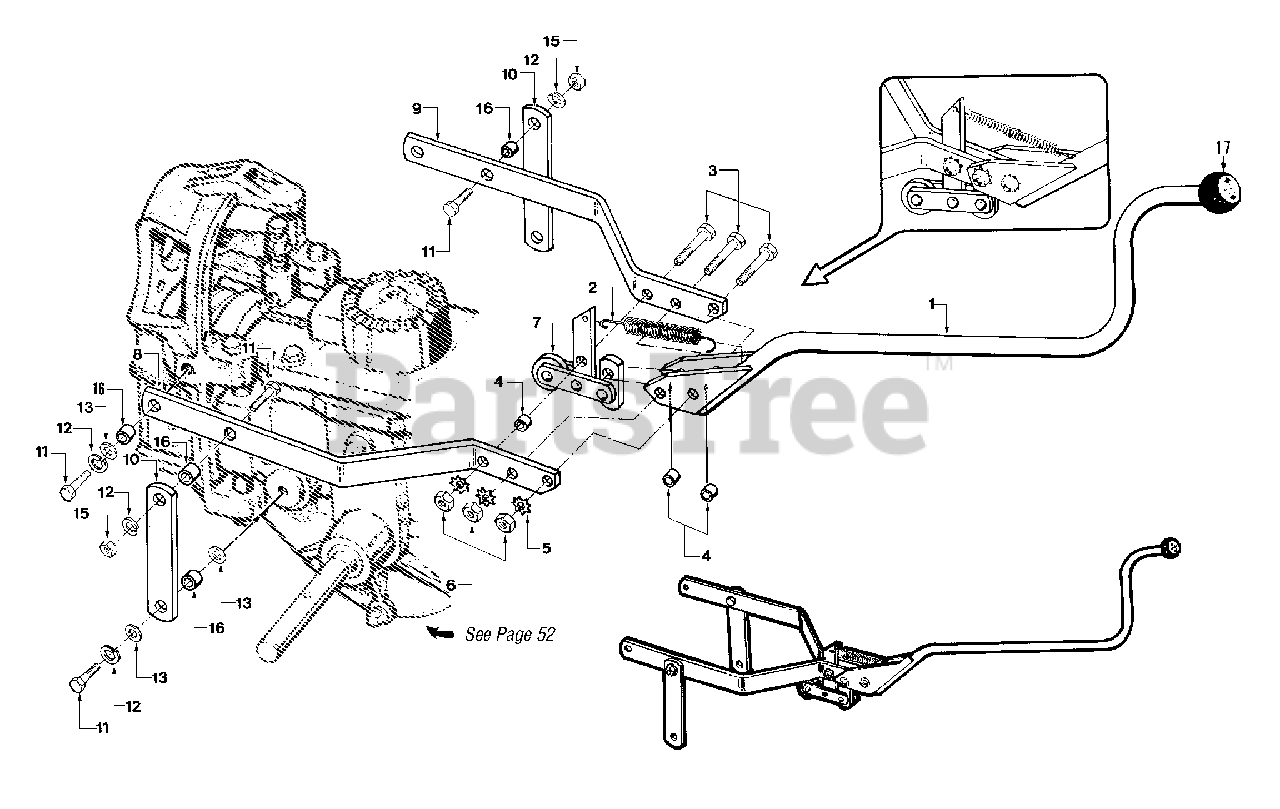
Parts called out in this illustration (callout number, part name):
1	Lever-Wheels/Tines/PTO Drive With Knob
2	Spring-clutch pawl
3	Bolt-hex hd., 5/16-18 x 1-1/2"
4	Bushing-3/8"
5	Lockwasher-external tooth, 5/16"
6	Nut-hex, 5/16"-18
7	Roller Assembly
8	Yoke-left side
9	Yoke-right side
10	Link-yoke pivot, left & right, 6-7/8" long
11	Bolt-hex hd., 3/8-16 x 1"
12	Lockwasher-spring lock, 3/8"
13	Washer-flat, 3/8", S.A.E
15	Nut-hex, 3/8"-16.
16	Bushing-spacer, 19/64" (.300")
17	Knob
